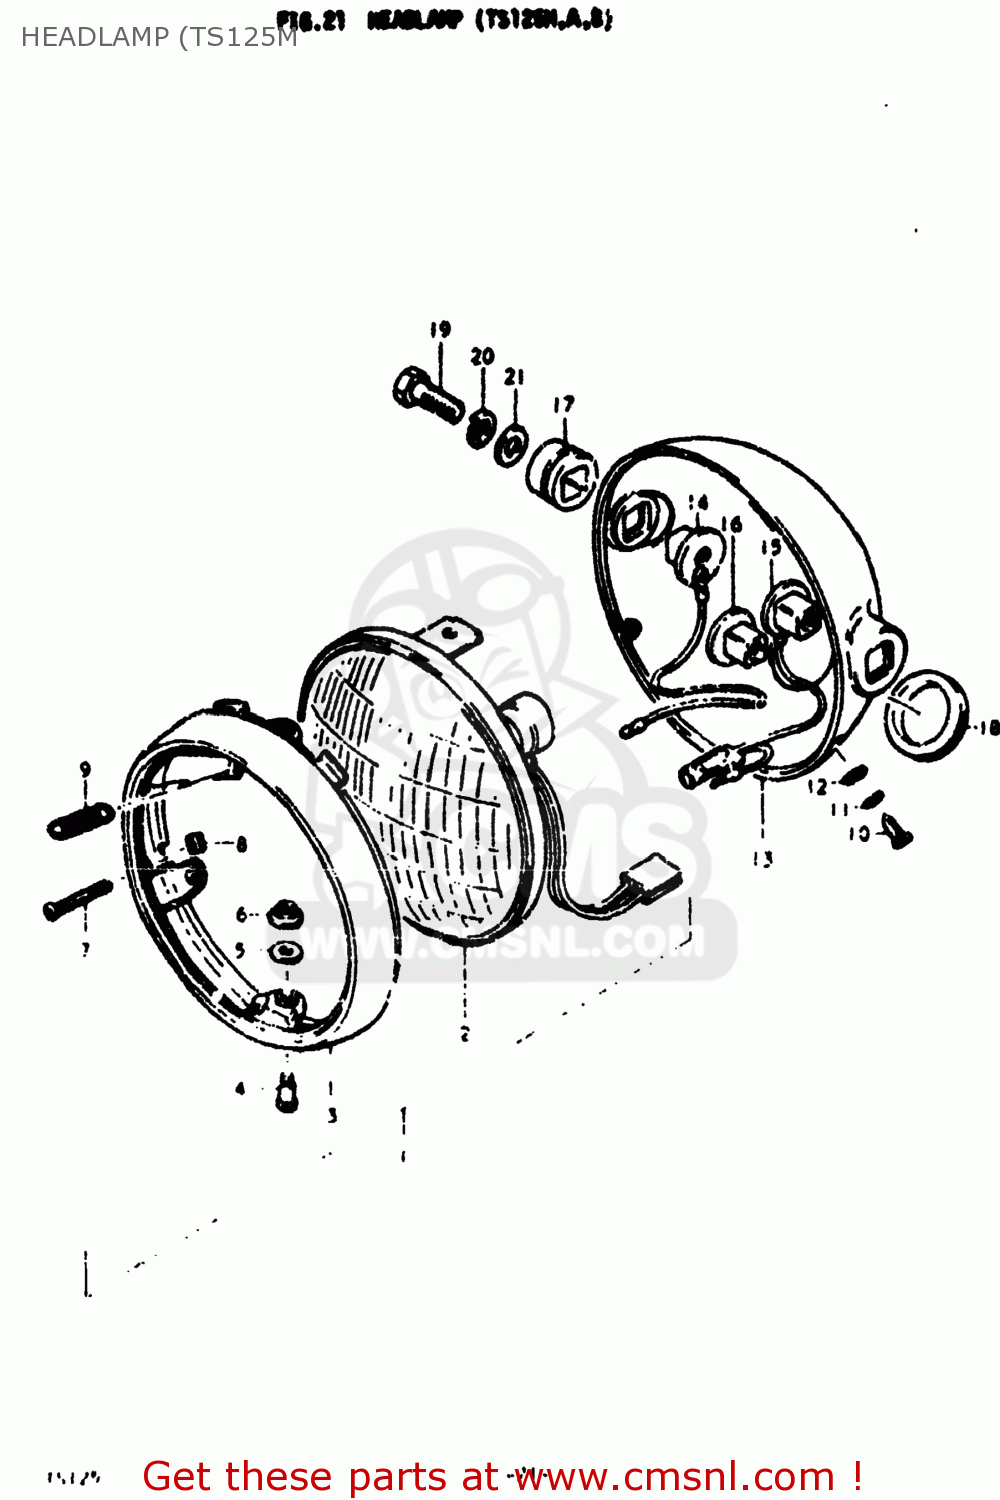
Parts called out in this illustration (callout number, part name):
1	HEADLAMP ASSEMBLY
2	LAMP UNIT
3	RIM,HEADLAMP
4	SCREW
5	SPACER,HEADLAMP UNIT
6	NUT,ADJUSTING
7	SCREW,HEADLAMP ADJUST
8	NUT,HEADLAMP ADJUSTER
9	SPRING,HEADLAMP ADJUST
10	SCREW
11	LOCK WASHER
12	WASHER
13	HOUSING COMP,HEADLAMP
14	SPACER,HEADLAMP HOUSING
15	SPACER,HEADLAMP HOUSING
16	SPACER,HEADLAMP HOUSING
17	CUSHION,HEADLAMP HOUSING
18	GROMMET,HEADLAMP HOUSING
19	BOLT
20	LOCK WASHER
21	WASHER
